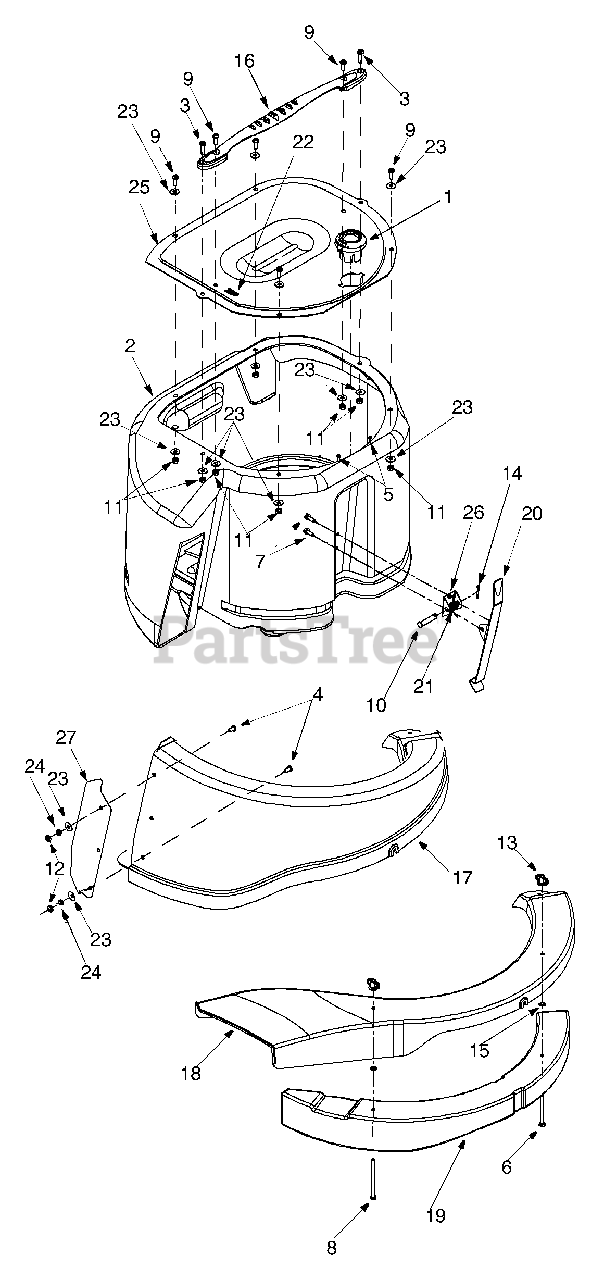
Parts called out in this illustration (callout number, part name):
1	Flow Indicator Assembly
2	Grass Bag Assembly
3	Machine Screw 1/4-20 x 1.0
4	Machine Screw 1/4-20 x 0.5"
5	Hex Screw #10-16 x 0.5"
6	Hex Screw 1/4-20 x 2.75"
7	Self-Tapping Screw 1/4-20 x 0.75"
8	Hex Screw 1/4-20 x 3.75"
9	Machine Screw 1/4-20 x 0.75"
11	Hex Sems Nut 1/4-20
12	Jam Nut
13	Wing Nut
15	Speed Nut
17	Discharge Chute: Grass Bag
18	Side-Discharge Chute
19	Mulching Plug
20	Bag Release Lever
21	Torsion Spring
24	Lock Washer
